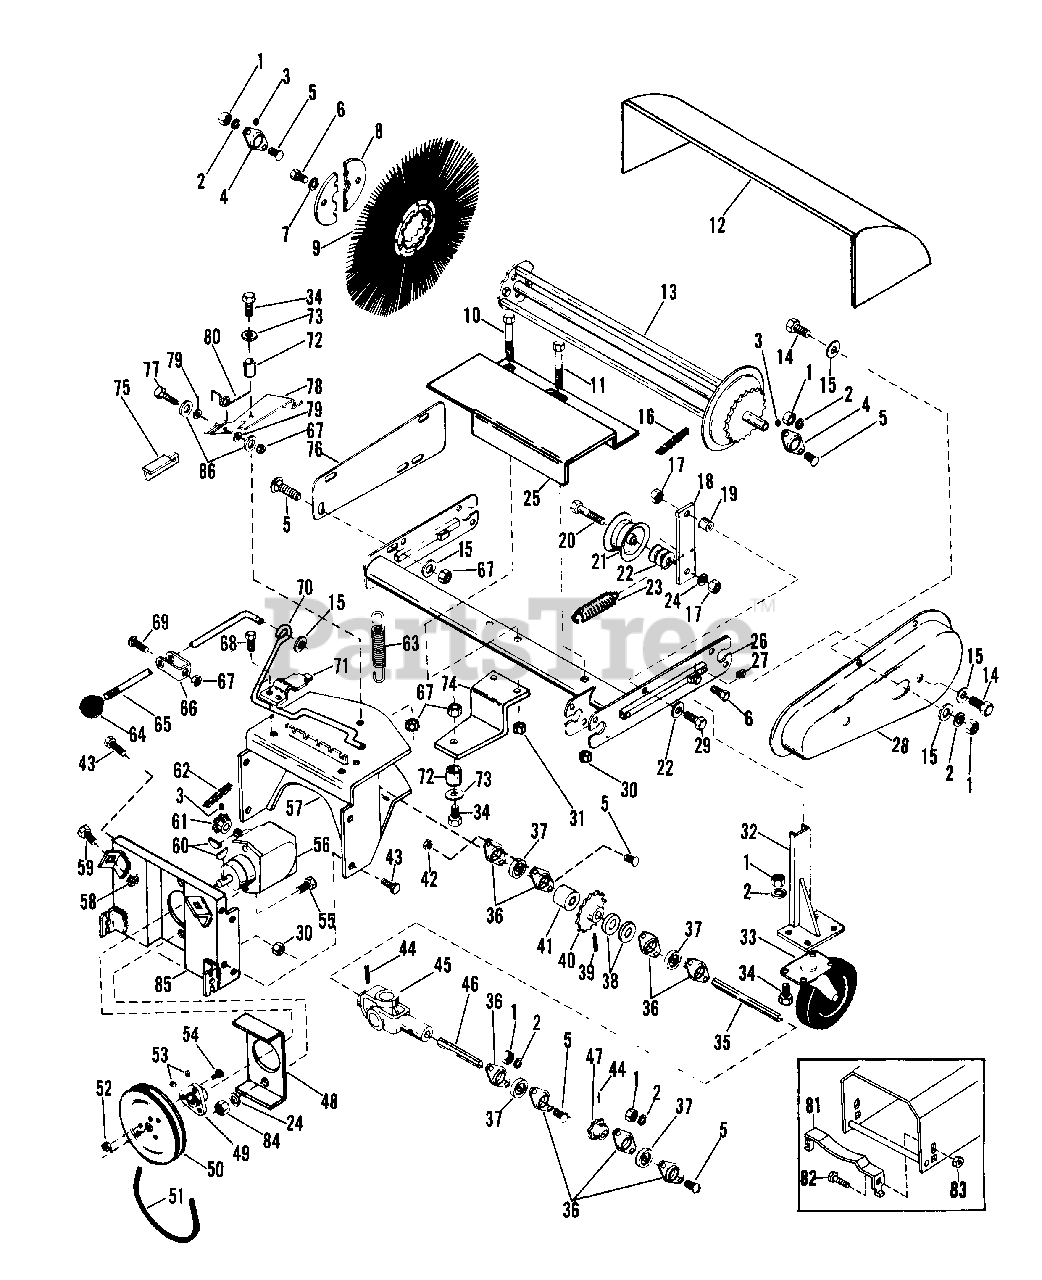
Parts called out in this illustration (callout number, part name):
1	NUT-HEX .312-18
2	WSHR-LK .312X.097 PL HVY
3	SCR-SET .25-20X.38 SKHCUPNL OH
4	BRG-FLG
5	BLT-RDHDSQNK .31-18X.75 GR5 PL
6	BLT-HEX .50-13X1.00 PL GR2
7	WSHR-LK .500X.151 HVY PL
8	RETAINER PLATE (SET OF 2)
9	BRUSH
10	BLT-HEX .38-16X3.50 PL GR5
11	BLT-HEX .38-16X3.00 PL GR2
14	BLT-HEX .31-18X1.00 PL GR 2
15	WSHR-FL-STL .38X.875X.083 PL
16	CHAIN
17	NUT-LK-CTR .375-16 GR A PL
18	IDLER ARM
19	BSHG-SLV .375X.437X.312
20	BLT-HEX .38-16X2.00 PL GR2
21	CHAIN TIGHTENER
22	WSHR-FL-STL .438X1.0X.083 PL
24	WSHR-LK .375X.115 HVY PL
25	SHAFT GUARD
26	BRUSH FRAME
27	NUT-SPEED U-TY .312-18
28	CHAIN SHIELD
29	BLT-HEX .38-16X1.00 PL
30	NUT-LK-FLG .375-16 GR A PL
31	NUT-LK TOP .375-16 GR C YWZC
32	CASTOR LEG
33	WHL, 5 DIA.
34	BLT-HEX .31-18X.75 PL GR2
36	BEARING FLANGE
37	BRG-BALL .884HEXX52MMX1.07
38	WSHR-FL-STL 1.015X1.500X.125
39	PIN-ROLL .188X1.75
40	SPROCKET
41	SPACER 1.006X1.307X.500
42	NUT-LK-TOP .312-18 GR C PL
43	BLT-HEX .38-16X.75 PL GR2
44	PIN-ROLL .188X1.50
45	JOINT, UNIVERSAL
46	DRIVE SHAFT
47	SPROCKET
48	STIFFENER PLATE
49	HUB
50	PLY-V 9.0 X 1.25 3BLT
51	V-BELT, 4L-RAW EDGE
52	NUT-FLG. .312-18 PL
53	SCR-SET .32-18X.38 SKHCUPNL OH
54	BLT-SERRDHD SL .31-18X.75 YZ
55	BLT-HEX .38-16X1.25 PL GR 2
56	GEAR BOX ASSEMBLY
57	ADAPTER FRAME
58	NUT-RETNR .38-16 TINRMAN
59	BLT-SCRHFWH .38-16X.75 PL
60	KEY-WDRF .188X.75X.313 SAE 9
61	SPROCKET
62	CHAIN
63	SG-TENS .060X.170X4.25 WLD ??
64	SHIFT BALL
65	POSITION ROD
66	BRACKET
67	NUT-LK .312-18 GR A PL
68	BLT-SERHFWH .31-18X.75 PL
69	BLT-RDHDSQNK .31-18X1.38SHT PL
70	RELEASE ROD
72	SPACER BUSHING .5 X .32 X .21
73	WSHR-FL-STL .328X1.0X.094
74	BOTTOM MOUNT
75	LATCH BAR
76	HOOD STRAP
77	BLT-HEX .31-18X2.00 PL GR2
78	TOP MOUNT
79	WSHR-FL-STL .380X.875X.179 PL
80	SG-TORS .109X.88X2.25
81	BELT RETAINER
82	BLT-HEX .25-20X.50 PL GR2
83	NUT-LK-CTR .250-20 PL
84	NUT-HEX .375-16
85	MOUNTING PLATE
86	WSHR-FL-STL .344X1.125X.063PL
